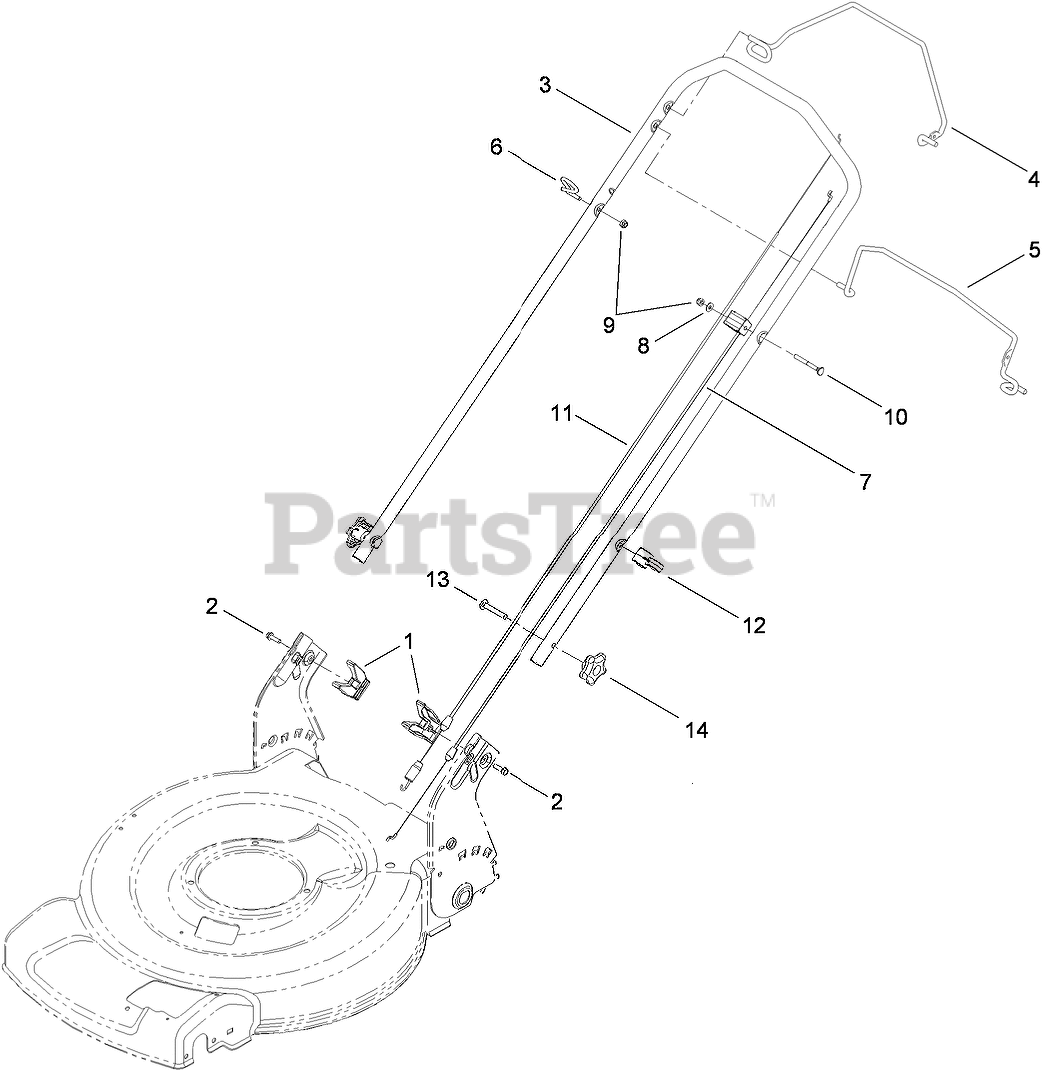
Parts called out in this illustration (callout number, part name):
1	ANCHOR-BAG
2	SCREW-HWH
3	HANDLE-CONTOUR
4	BAIL-TRACTION
5	BAIL-BRAKE
6	GUIDE-ROPE
7	CABLE-BRAKE, 2 BAIL
8	WASHER-FLAT
9	NUT-LOCK, NI
10	SCREW-HANDLE
11	CABLE-TRACTION
12	Guide-Cable
13	Screw-CARR
14	KNOB-HANDLE
